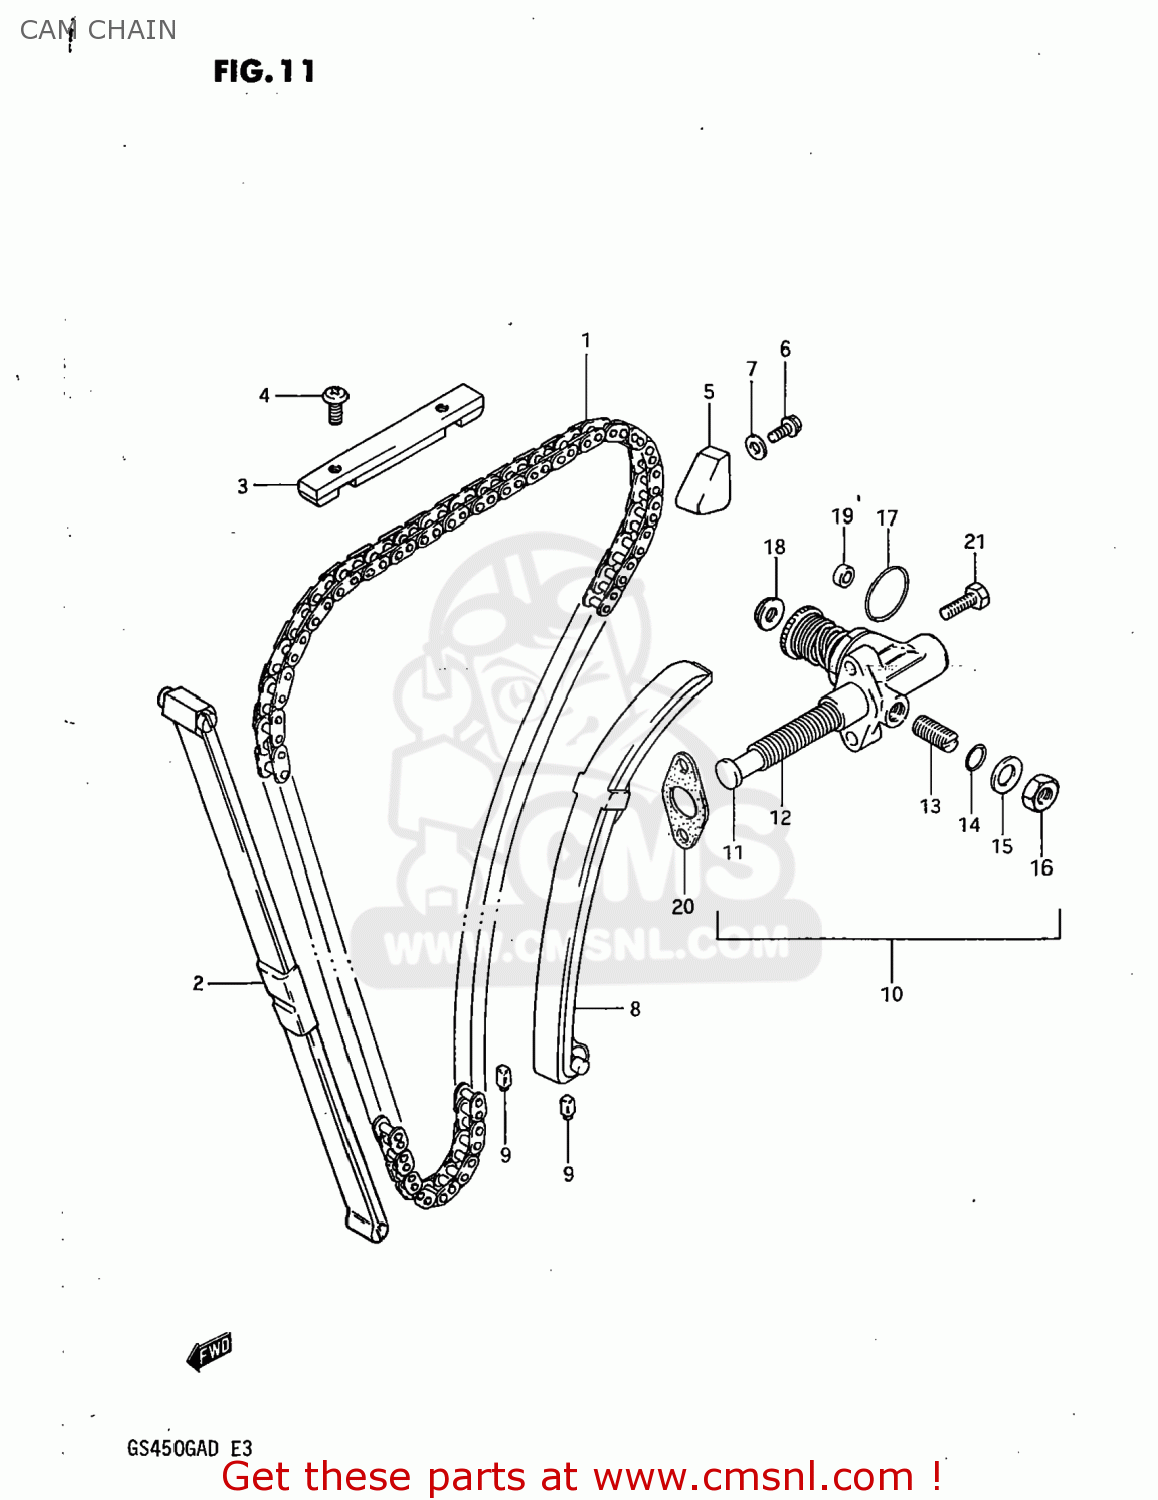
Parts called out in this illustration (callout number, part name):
1	CHAIN,CAMSHAFT DRIVE(120L)
2	GUIDE,CAM CHAIN NO.1
3	GUIDE,CAM CHAIN NO.3
4	SCREW
5	GUIDE,CAM CHAIN
6	BOLT
7	WASHER
8	TENSIONER,CAM CHAIN
9	CUSHION,CAM CHAIN TENSIONER
10	ADJUSTER ASSEMBLY,TENSIONER
11	ROD,PUSH
12	SPRING
13	SCREW
14	O RING(D:1.9,ID:5.7)
15	WASHER
16	NUT
17	O RING(D:2.4,ID:20.8)
18	NUT
19	SEAL,OIL(10X16X4)
20	GASKET,TENSIONER ADJUSTER (MCA)
21	SCREW (6X25)
